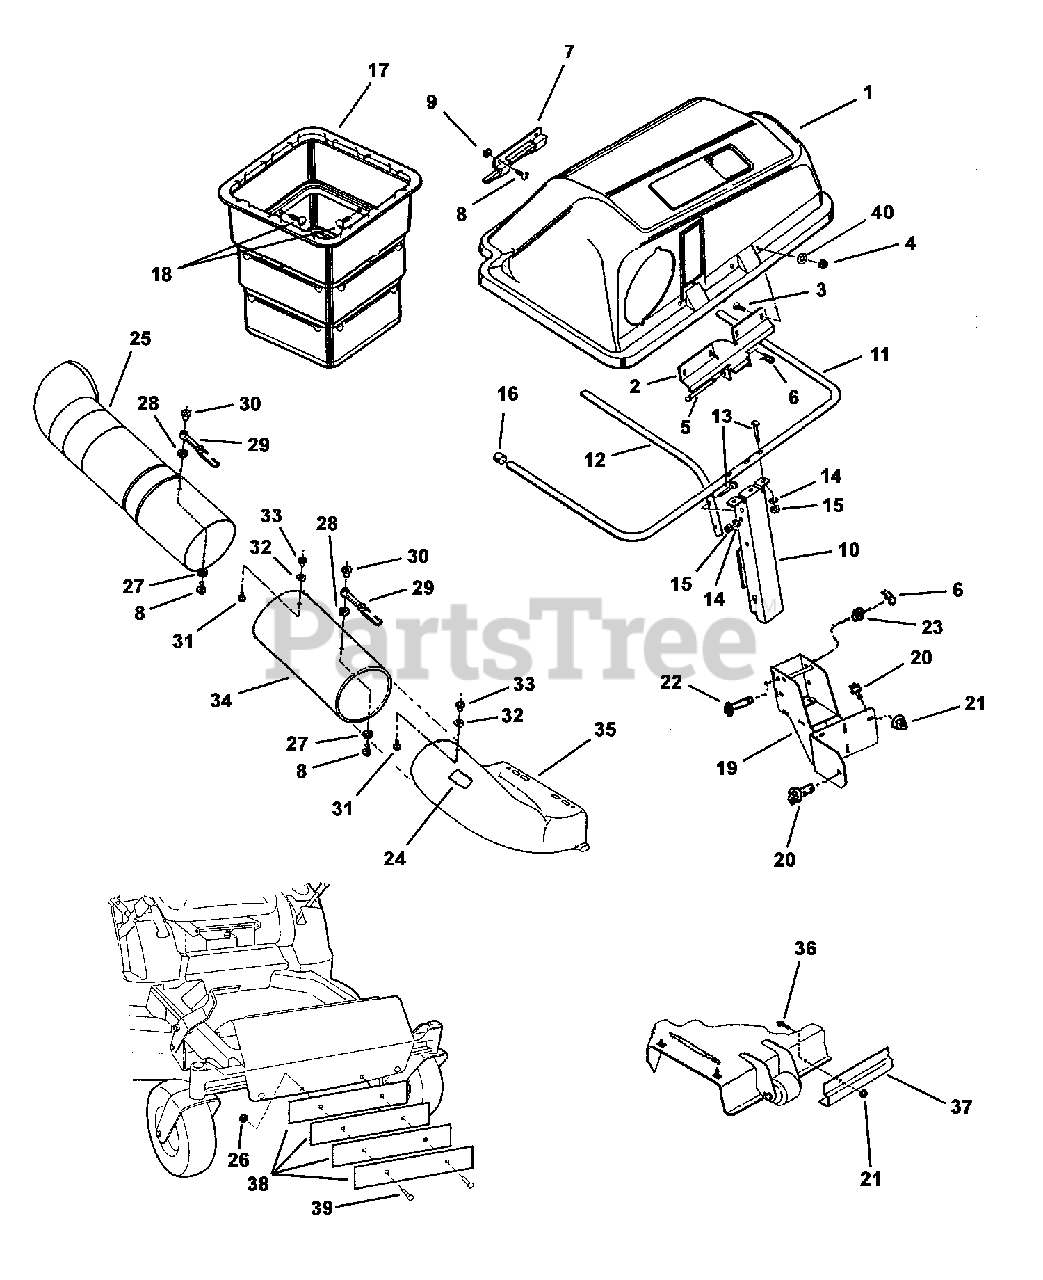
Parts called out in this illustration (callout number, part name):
1	ASSY., TWIN COVER - 38/42
2	HINGE, COVER
3	* BOLT, SHORT NECK CARRIAGE 1/4-20 X 3/4
4	* NUT, HEX CENTER LOCK 1/4-20 YELLOW ZINC
5	* PIN, COVER HINGE
6	* PIN, HAIR, 3/32 X 1.5 YZ
7	HANDLE, COVER
8	* SCREW, PAN HEAD CROSS RECESS 10-24 X 5/8
9	* NUT, HEX LOCK 10-24 UNC-2B W/NYLON INSERT
10	WELD, CHANNEL SUPPORT
11	TUBE, U
12	TUBE, CENTER
13	* BOLT, CARRIAGE HEAD 5/16-24 X 1-5/8
14	* WASHER, SPLIT LOCK .32 X .58 X .08 YZ
15	* NUT, HEX 5/16-24 GR5 YZ
16	* CAP, TUBE END
17	ASSEMBLY, NESTABLE CONTAINER - TWIN CATCHER
18	* PANEL FASTENER
19	WELDMENT, GRASS CATCHER SUPPORT - RZT
20	* SCREW, HEX WASHER SELF TAP 5/16-18 X 3/4-YZ
21	* NUT, FLANGED LOCK 5/16-18 YZ
22	* PIN, CLEVIS - 1/2" X 4.160 YZ
23	* WASHER, SAE 1/2
24	DECAL, CHUTE/DEFLECTOR
25	TUBE, UPPER - TWIN BAGGER - 38" & 42" RZT
26	* NUT, HEX LOCK 5/16-18-3B YZ ESNA
27	* WASHER, FLANGED LOCK .219X.500X.049 BL
28	* WASHER, FLAT .190 I.D. X .75 O.D. YZ
29	* STRAP, MOUNTING BAG ADAPTER/TUBE
30	* NUT, WELD-10/24 THREAD
31	* SCREW, CROSS RECESSED PAN HEAD 5/16-18 X 5/8
32	* WASHER, FACETED .34X.69X.08
33	* TEENUT, 5/16-18 THREAD
34	TUBE, LOWER - TWIN BAGGER - 42" RZT
35	CHUTE ASSY (includes decal)
36	* SCREW, PAN HEAD MACHINE 5/16-18 X 3/4 YZ
37	BAFFLE, 42" DECK - RZT
38	BALLAST-TWIN BAG CATCHER - RZT
39	BOLT, SHORT NECK CARRIAGE 5/16-18 X 1.75 GR5 YZ
40	WASHER, SAE 1/4
